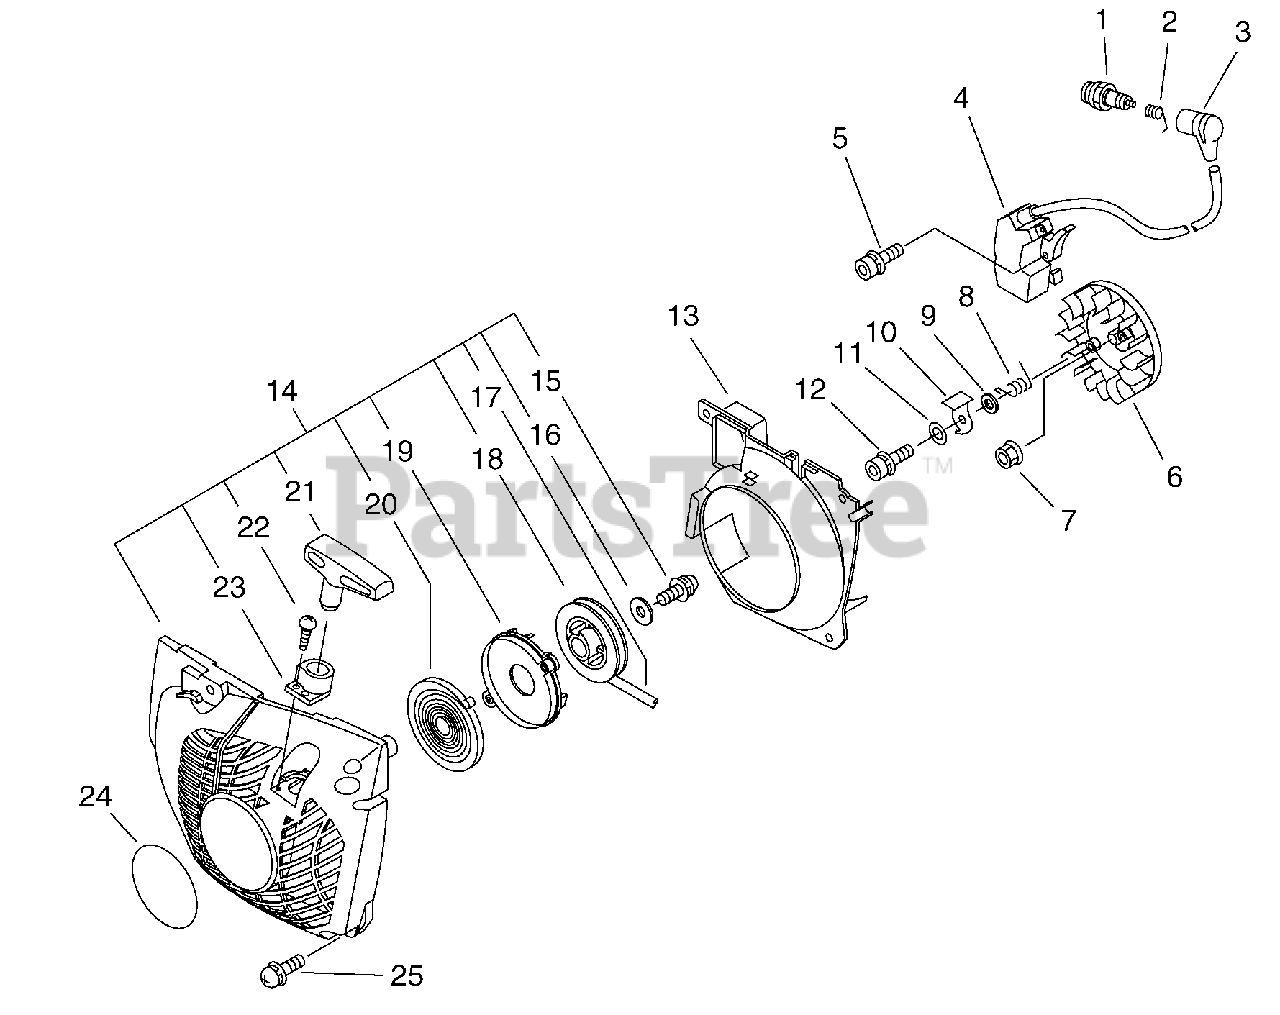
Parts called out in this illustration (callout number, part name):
1	SPARK PLUG -- BPM-8Y
2	TERMINAL, SPARK PLUG CAP
3	CAP, SPARK PLUG
4	COIL, IGNITION
5	SCREW - 4X30
6	FLYWHEEL
7	NUT - 8 -- FLANGE
8	SPRING, RETURN
9	WASHER - 5
10	PAWL, STARTER
12	SCREW - 5X14
13	COVER, FAN
14	STARTER ASSY
15	SCREW - 5X12
17	ROPE, STARTER - 3.5X960
18	REEL, ROPE
19	PLATE, STARTER
20	SPRING, REWIND
21	GRIP, STARTER
22	SCREW - 3X14
23	GUIDE, ROPE
24	LABEL - ECHO
25	SCREW - 5X18
